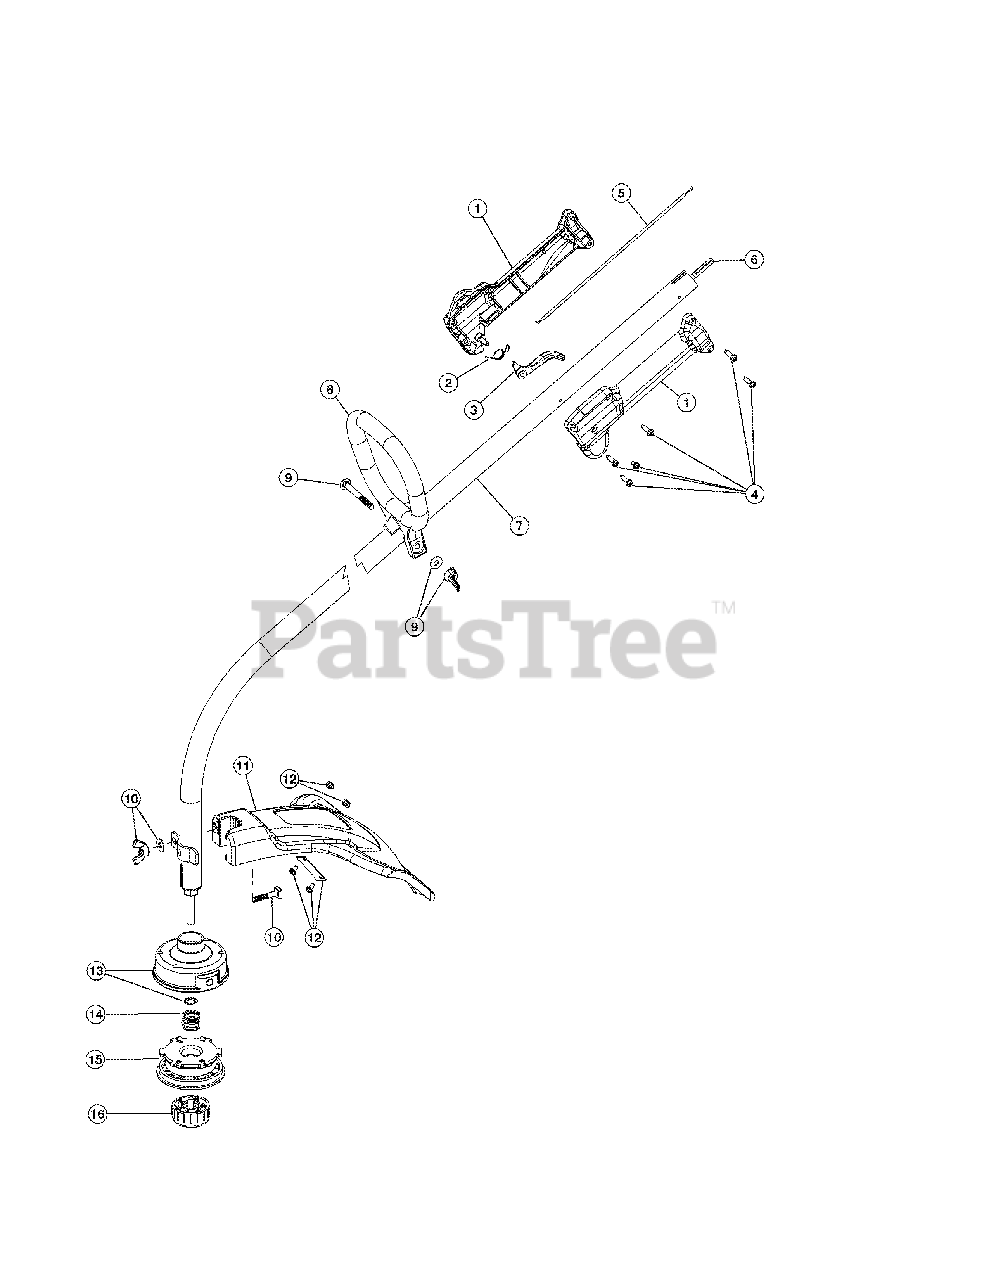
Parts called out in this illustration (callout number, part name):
1	Throttle Housing and Trigger Assembly(includes 2 & 3)
2	Throttle Trigger Spring
3	Throttle Trigger
4	Throttle Housing Screws
5	Throttle Cable
6	Flexible Drive Shaft
7	Drive Shaft Housing Assembly (includes 6 & 13)
8	D-Handle Assembly (includes 9)
9	D-Handle Hardware
10	Guard Mounting Hardware
12	Blade Assembly
13	Outer Reel w/Retainer
14	Spring
15	Inner Reel
16	Bump Knob
